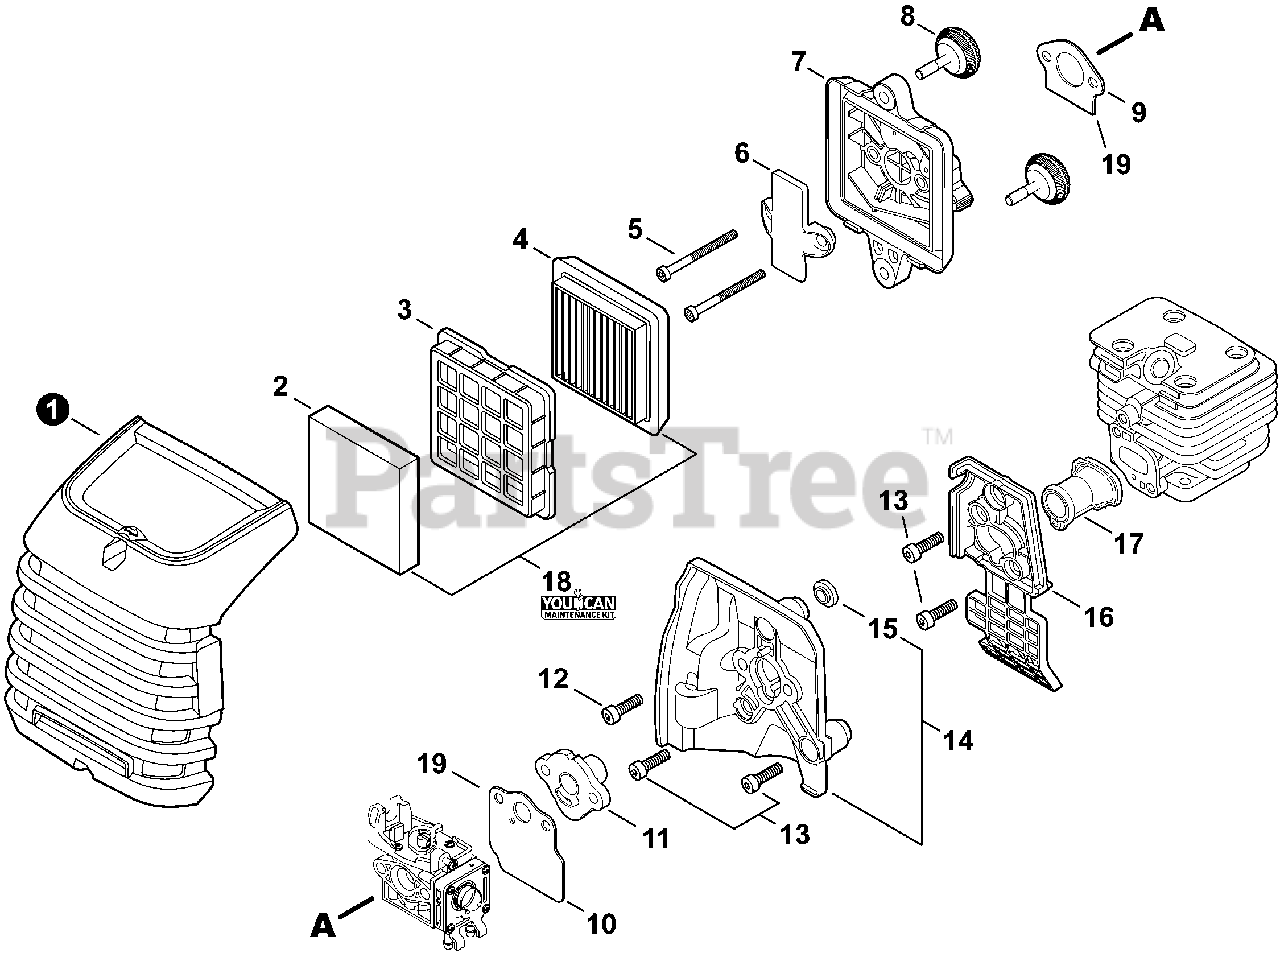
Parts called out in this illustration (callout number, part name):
1	COVER, AIR FILTER
2	PRE-FILTER, FOAM
3	RETAINER, PRE-FILTER
4	FILTER, AIR
5	BOLT, TORX 5×60
6	PLATE, PREVENT
7	CASE, AIR FILTER
8	THUMBSCREW
9	GASKET, INTAKE
10	HEAT SHIELD, INTAKE
11	BOOT, INSULATOR PLATE
12	BOLT, TORX 5×20
13	BOLT, TORX 5×16
14	PLATE, INSULATOR
15	COLLAR 5
16	HOLDER, BELLOWS
17	BELLOWS, INTAKE
18	TUNE-UP KIT - YOUCAN™
19	GASKET KIT
